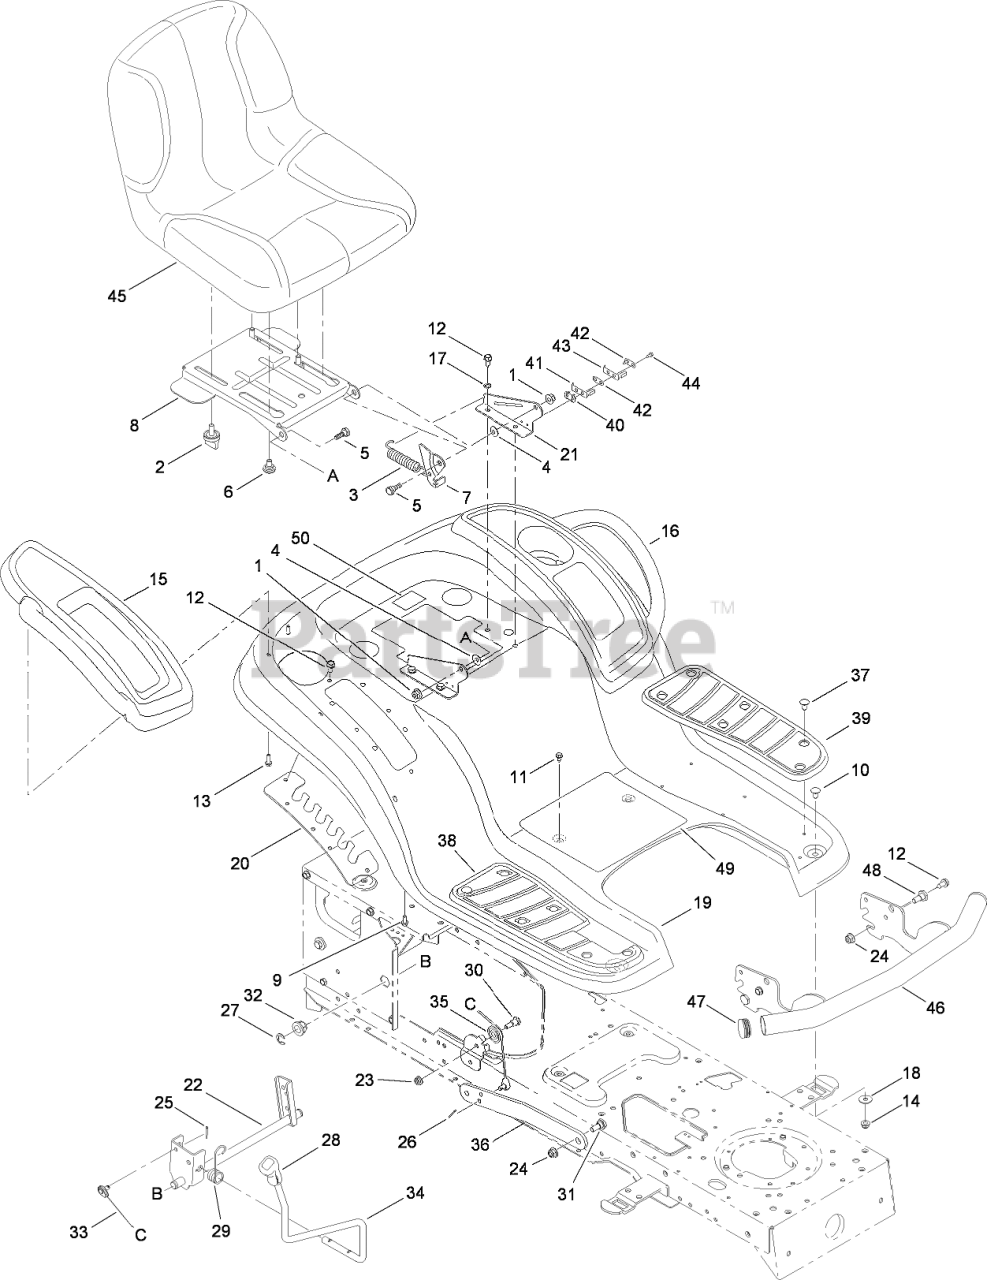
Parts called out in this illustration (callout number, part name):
1	NUT-LOCK, FLANGE
3	SPRING-EXTENSION
4	WASHER-BELL
5	BOLT-SHOULDER
6	BOLT-SHOULDER
7	BRACKET-LIFT, LH
8	BRACKET-PIVOT, SEAT
10	BOLT-CARR
11	SCREW-HWHTF
12	SCREW-TAP
13	SCREW-TAP
14	NUT-LOCK, FLANGE
15	COVER-FENDER, RH
16	COVER-FENDER, LH (W/CUPHOLDER)
17	WASHER-LOCK, EXTERNAL
18	WASHER-FLAT
19	FENDER
20	BRACKET-ADJUSTING, LIFT
21	BRACKET-MOUNT, SEAT
22	LIFT SHAFT ASM
23	NUT-LOCK, FLANGE
24	NUT-LOCK, FLANGE
25	PIN-COTTER
26	PIN-COTTER
27	RING-E
28	GRIP-HANDLE
29	SPRING-TORSION
30	BOLT-SHOULDER
31	BOLT-SHOULDER
32	BEARING-FLANGE
33	CABLE-LIFT
34	HANDLE-LIFT
35	PULLEY-ROLLER
36	ARM-LIFT
37	CLIP-RATCHET, FASTENER
38	PAD-FOOT, RH
39	PAD-FOOT, LH
40	PLATE-BOSS, INSULATOR
41	SWITCH-SPRING, INNER
42	PLATE-INSULATOR
43	SWITCH-SPRING
44	SCREW-HWHTF
45	SEAT-MEDIUM BACK
46	BUMPER ASM
47	CAP-HUB
48	BOLT-SHOULDER
49	DECAL-INSTRUCTIONS, OPERATOR
50	DECAL-SERVICE
